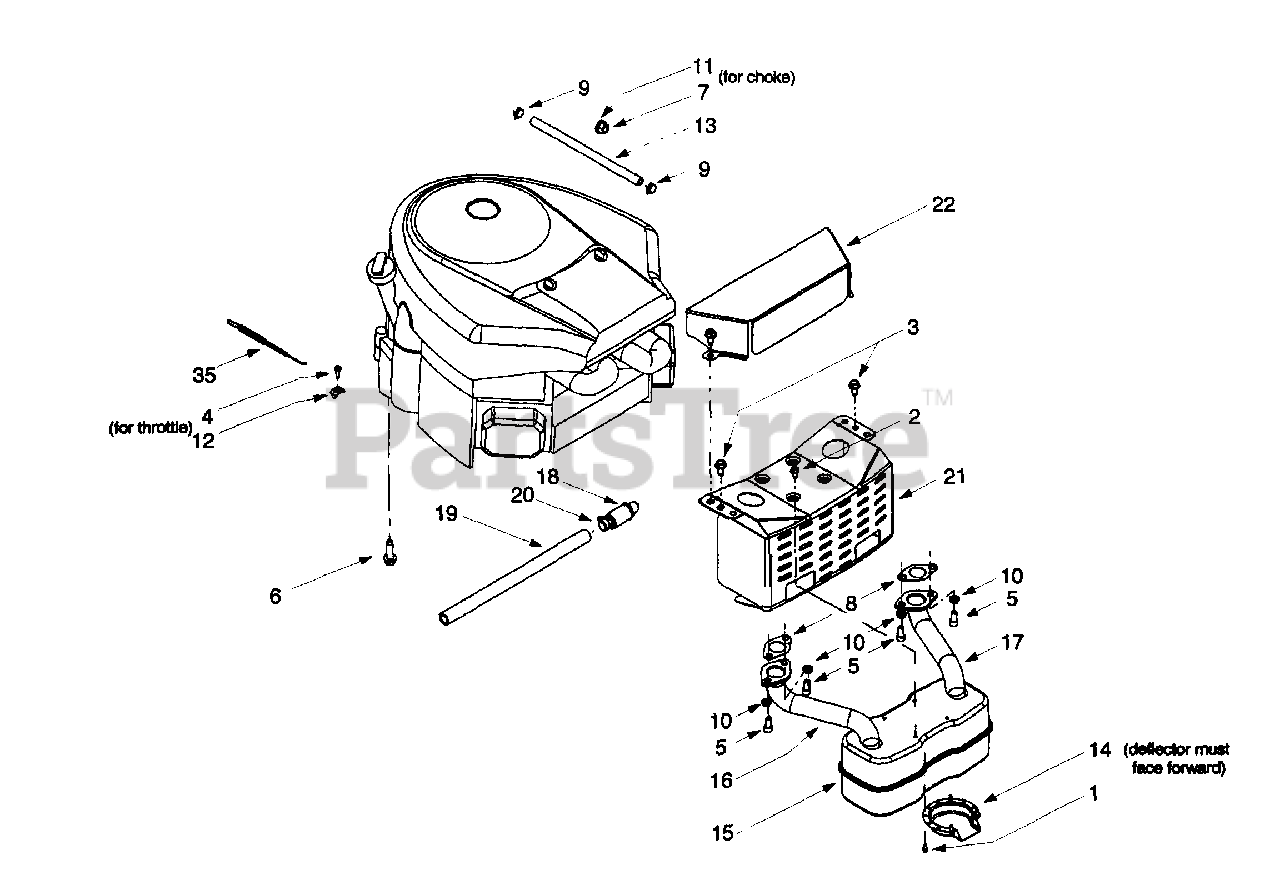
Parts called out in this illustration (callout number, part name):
1	Self Tapping Screw, #8-32 x .375
2	Self Tapping Screw, 1/4-20 x .5
3	Self Tapping Screw, 5/16-18 x .625
4	Screw, #10-32 x .625
5	Socket Cap Screw, 5/16-18 x .625
6	Self Tapping Screw, 3/8-16 x 1.25
7	Hex Nut, 3/8-16
8	Exhaust Gasket
9	Hose Clamp
10	Lock Washer, 5/16
11	Flat Washer, 3/8 x .56 x .018
12	Casing Clamp
13	Fuel Line Hose
14	Muffler Deflector
15	Muffler, Twin Inlet
16	RH Exhaust Pipe
17	LH Exhaust Pipe
18	Oil Drain Valve
19	Oil Drain Hose
20	Oil Drain Cap
22	Engine Heat Shield
35	Throttle Cable
